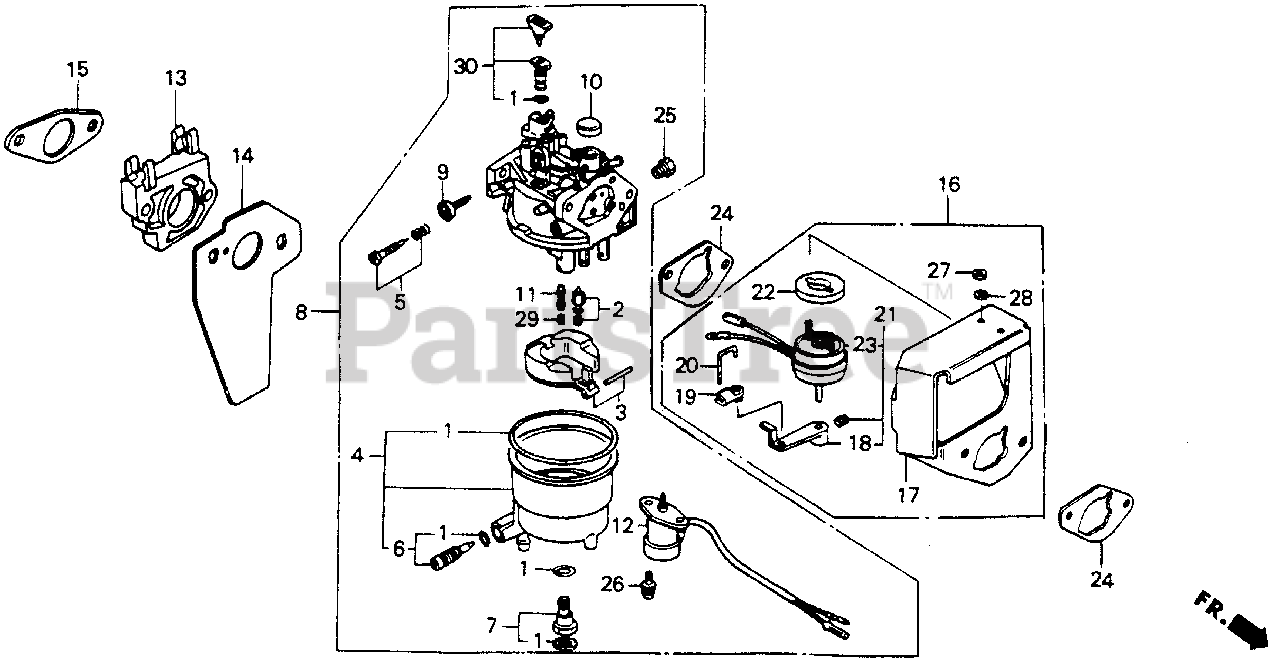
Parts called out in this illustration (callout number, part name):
1	GASKET SET
2	VALVE SET, FLOAT
3	FLOAT SET
4	CHAMBER SET, FLOAT
5	SCREW SET, PILOT
6	SCREW SET, DRAIN
7	SCREW SET
8	CARBURETOR ASSY. (BE38B E)
9	SCREW, THROTTLE STOP
10	CAP, CHOKE LEVER DUST
11	NOZZLE, MAIN
12	VALVE ASSY., SOLENOID
13	INSULATOR, CARBURETOR
14	GASKET, CARBURETOR
15	GASKET, INSULATOR
16	STAY ASSY., SOLENOID
17	STAY, CHOKE SOLENOID
18	LEVER, CHOKE SOLENOID
19	JOINT, ROD
20	ROD, CHOKE SOLENOID
21	SOLENOID ASSY., CHOKE
22	SPACER, CHOKE SOLENOID
23	SOLENOID, ROTARY CHOKE
24	GASKET, AIR CLEANER
25	NUT, JOINT
26	SCREW-WASHER (6X12)
27	NUT, HEX. (3MM)
28	WASHER, SPRING (3MM)
29	JET, MAIN (#90)
29	JET, MAIN (#92)
29	JET, MAIN (#95)
30	JET SET, PILOT (#35)
